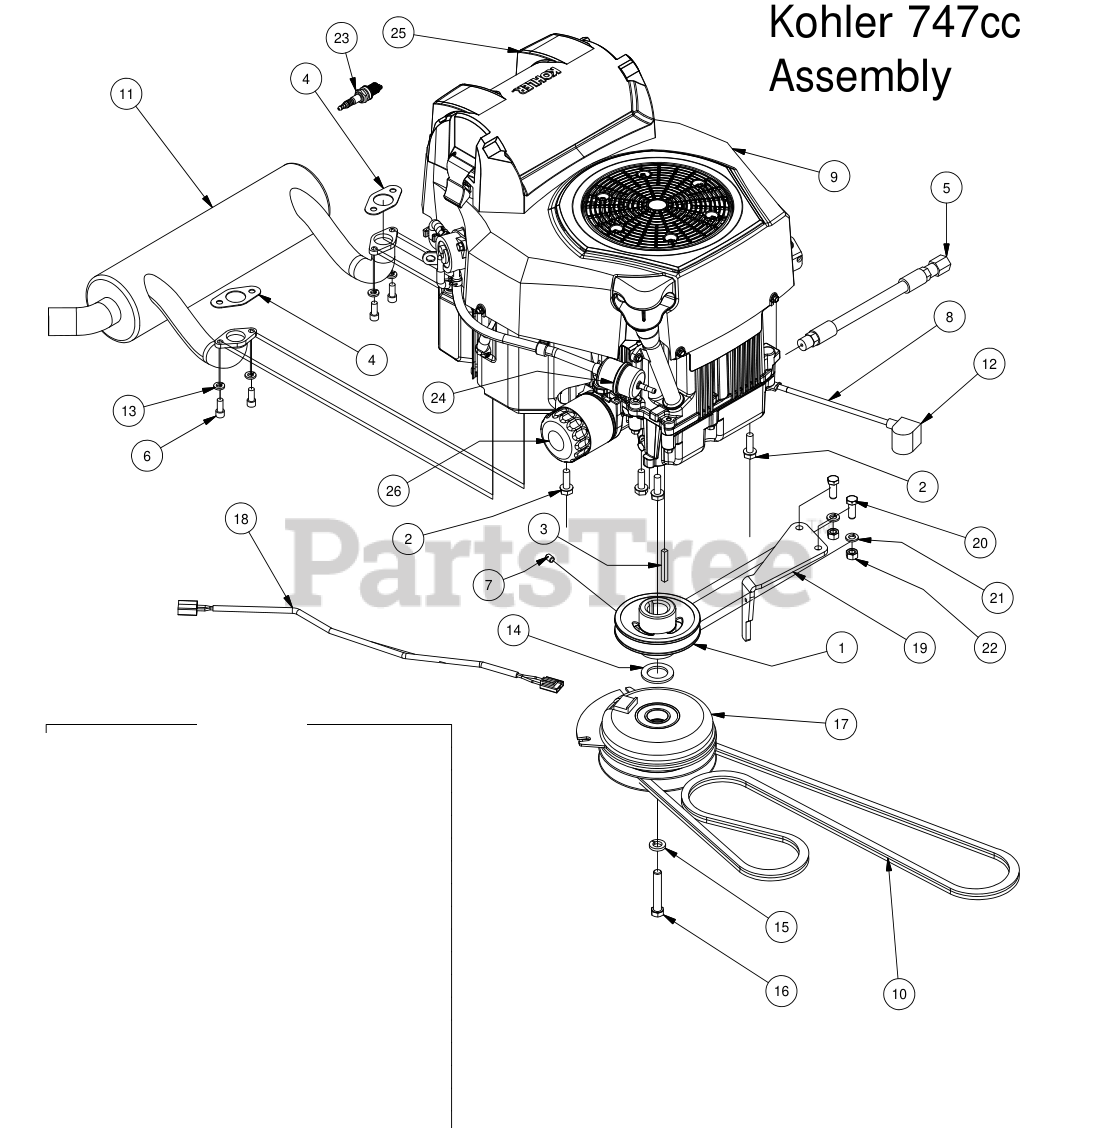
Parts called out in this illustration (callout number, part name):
1	4 3/4 Motor Pulley
2	3/8 x 1 1/8 bolt
3	1/4 x 2 Square key Stock
4	Exhaust Gasket
5	Oil drain Valve
6	5/16-18 x 3/4 Socket C/S
7	5/16 Set Screw
8	Ground Cable
9	Kohler-2014 CZT/Outlaw 747cc
11	2014 Kohler Outlaw Muffler
12	Black Boot For Ground Cable
13	5/16" Lock Washer
14	1 1/8" Flat Spacer
15	7/16" Lock Washer
16	7/16" x 2 1/2" Hex Bolt
17	Clutch Assembly
18	Clutch Pigtail
19	PTO Engager Holder
20	3/8" x 1" Hex Bolt
21	3/8" Lock Washer
22	3/8" Hex Nut
23	Spark Plug
24	Universal Inline Fuel Filter
25	747 Kohler Air Filter
26	725 & 747 Kohler Oil Filter
